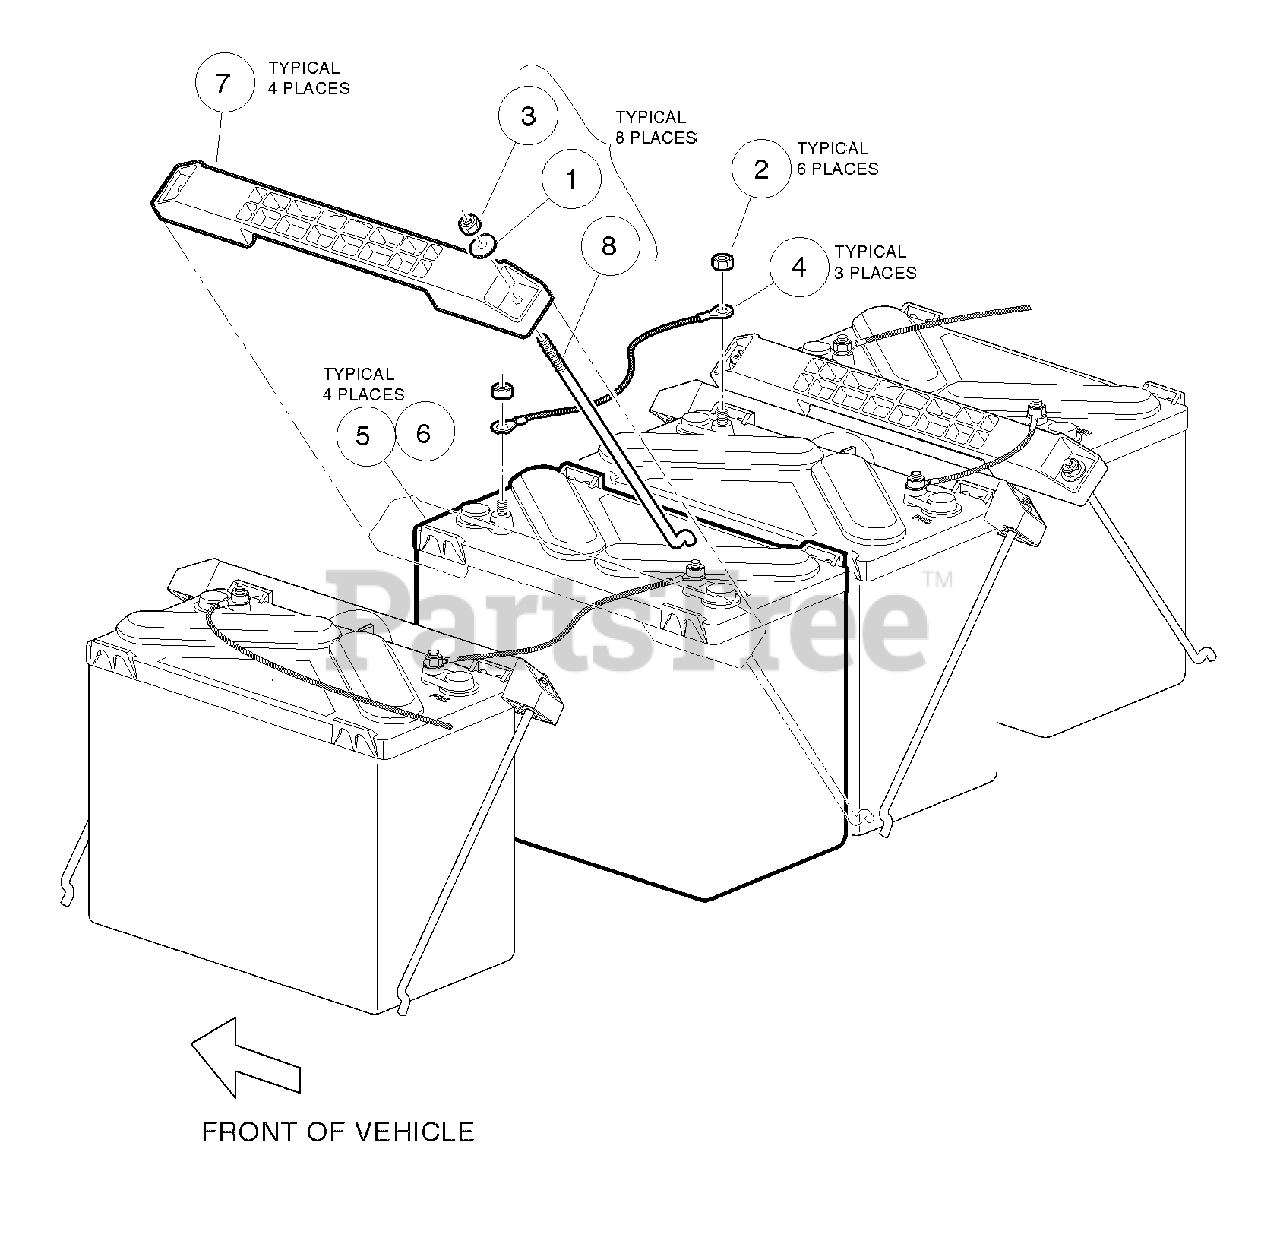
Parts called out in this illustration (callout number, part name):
1	Washer, 5/16 Flat
2	Nut, 5/16-18 Stainless-Steel Hex
3	Locknut, 5/16-18 Nylon Insert
4	Asm, Wire, #6blk 13in
5	Battery, Ventmaster 12-Volt
6	Battery, Ventmaster 12-Volt
7	Battery Hold-Down
8	Bolt, Battery, J-
